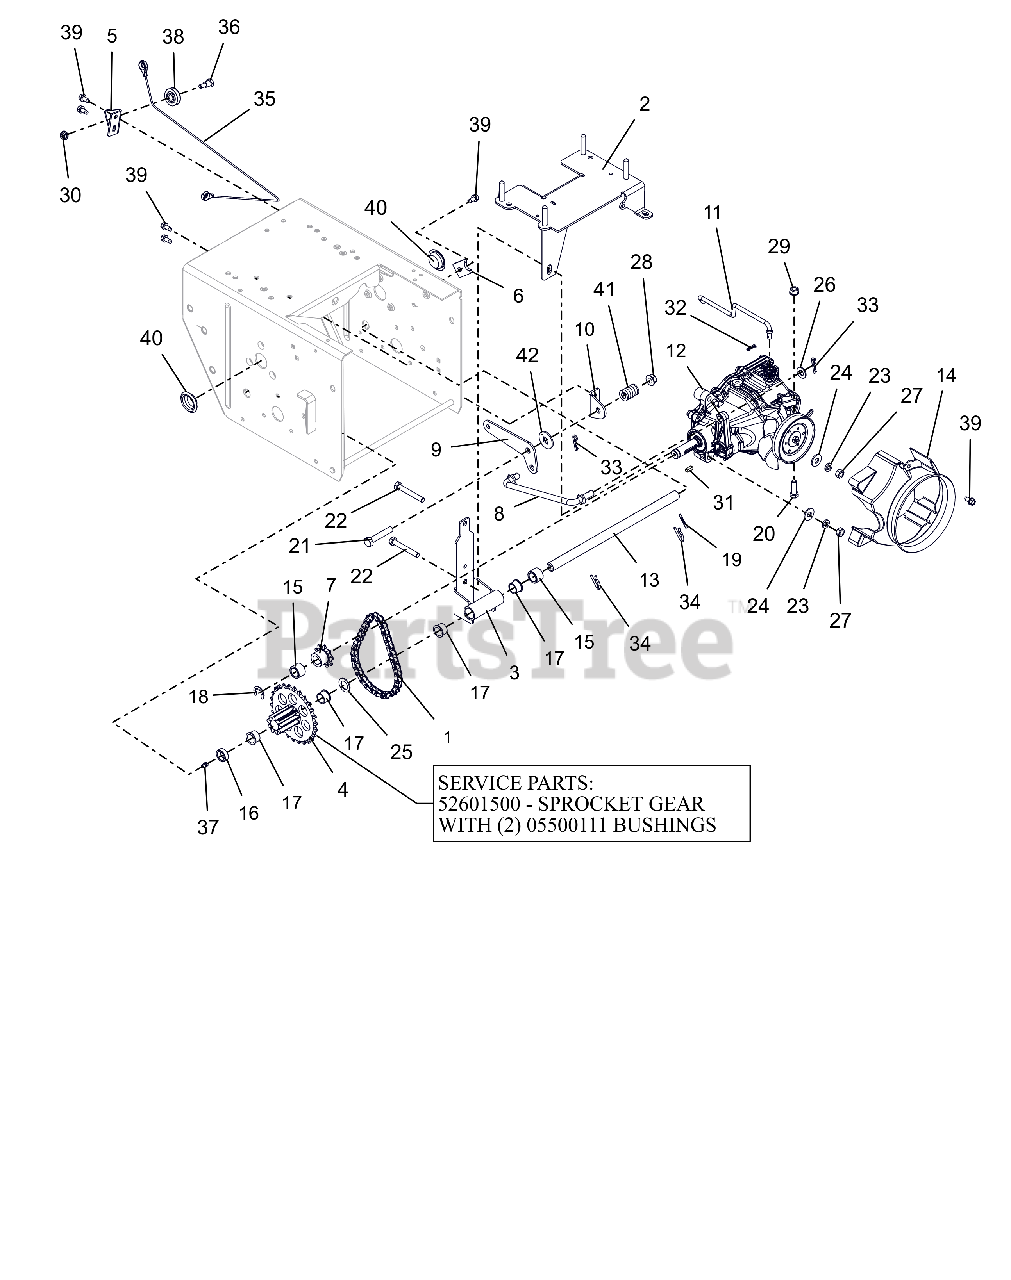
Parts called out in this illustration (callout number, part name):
1	CHAIN - #41, 32 PITCHES
2	BRACKET, HYDROSTATIC TRANS XLG
3	TRANS MOUNT, TENSIONING, WHEEL
4	PINION & SPROCKET
4	PINION & SPROCKET W/BUSHINGS
5	BRACKET, CABLE PULLEY
6	TAB, ANTI ROTATION
7	SPROCKET, PINION 9T W/KEY
8	ROD, HYDRO TRANS SHIFT
9	PIVOT, HYDRO TRANS SHIFT
10	BRACKET, HYDRO SHIFT PIVOT
11	ROD, HYDRO BYPASS
12	TRANSMISSION, HYDROSTATIC
13	SHAFT, PINION - HARDENED
14	SHROUD, HYDROGEAR RT-310
15	SPACER, .635X.880X.611
16	BSHG-SLV, .635X.880X.305
17	BSHG-FLG .625X.750X.500X.875
18	RG-RTNG-EXT .625X.042
19	@PIN-GRV .125X1.00 TP E ALLOY
20	BLT,HEX .31-18X1.00 G5 ZCC
21	BLT,HEX .38-16X2.00 G5 ZCC
22	BLT, HEX .31-18X2.25 G5 ZCC
23	WSHR, LK-HVY .312X.097 ZCC
24	WSHR,FLT .375X.875X.083 ZCC
25	WSHR, FLT .630X1.005X.062 ZCC
26	WSHR,FLT .406X.812X.065 ZCC
27	NUT, HEX .312-18 ZCC
28	NUT-LK-TOP-FLG .38-16 ZC120
29	NUT-LK-TOP-FLG .312-18 GF ZCC
30	NUT-LK-TOP-FLG .250-20 GF ZCC
31	KEY-SQ .187 X .50 X .187
32	PIN, HAIR #178 .06X.77 ZCC
33	PIN, HAIR #213 .08X1.19 ZCC
34	PIN, SPRING CLIP
35	CABLE, TRACTION, HYDRO PRO
36	BOLT, SHLDR -.375 X .375 X .25-20
37	ZERK,FITTING .25X.125 DRIVE IN
38	PULLEY, CABLE
39	SCR-TAP .25-20X.50 HWH ZCC
40	PLUG, HOLE - 1.125"
41	SG-COMP .187X.56X1.62
42	FRICTION WASHER
